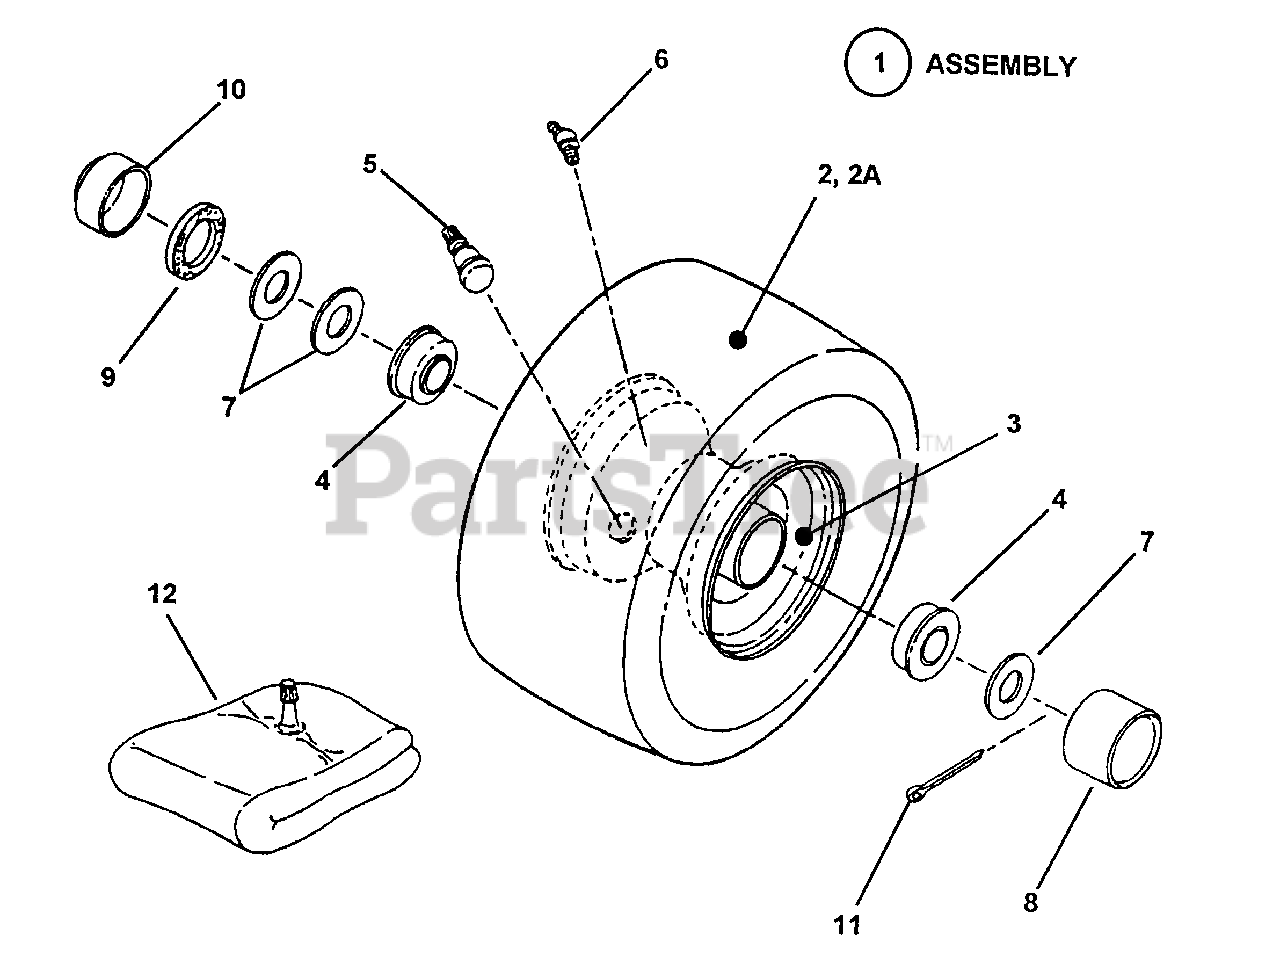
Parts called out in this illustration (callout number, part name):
1	ASSEMBLY, Front Tire & Rim 11x4.00-4
1	ASSEMBLY, Front Tire & Rim 11x4.10-4
2	TIRE, 11X4.00-4, KENDA
2A	TIRE, 11X4.10-4, CARLISLE
3	RIM - Monitor
3	RIM - Carlisle
4	BEARING, Ball
5	VALVE, Air (Snap-in)
6	FITTING Lube
7	WASHER, 3/4" I.D.
8	CAP, Hub
9	SEAL, Felt
10	CAP, Dust
11	PIN, Cotter 5/32 x 1"
12	TUBE, Inner (Optional)
